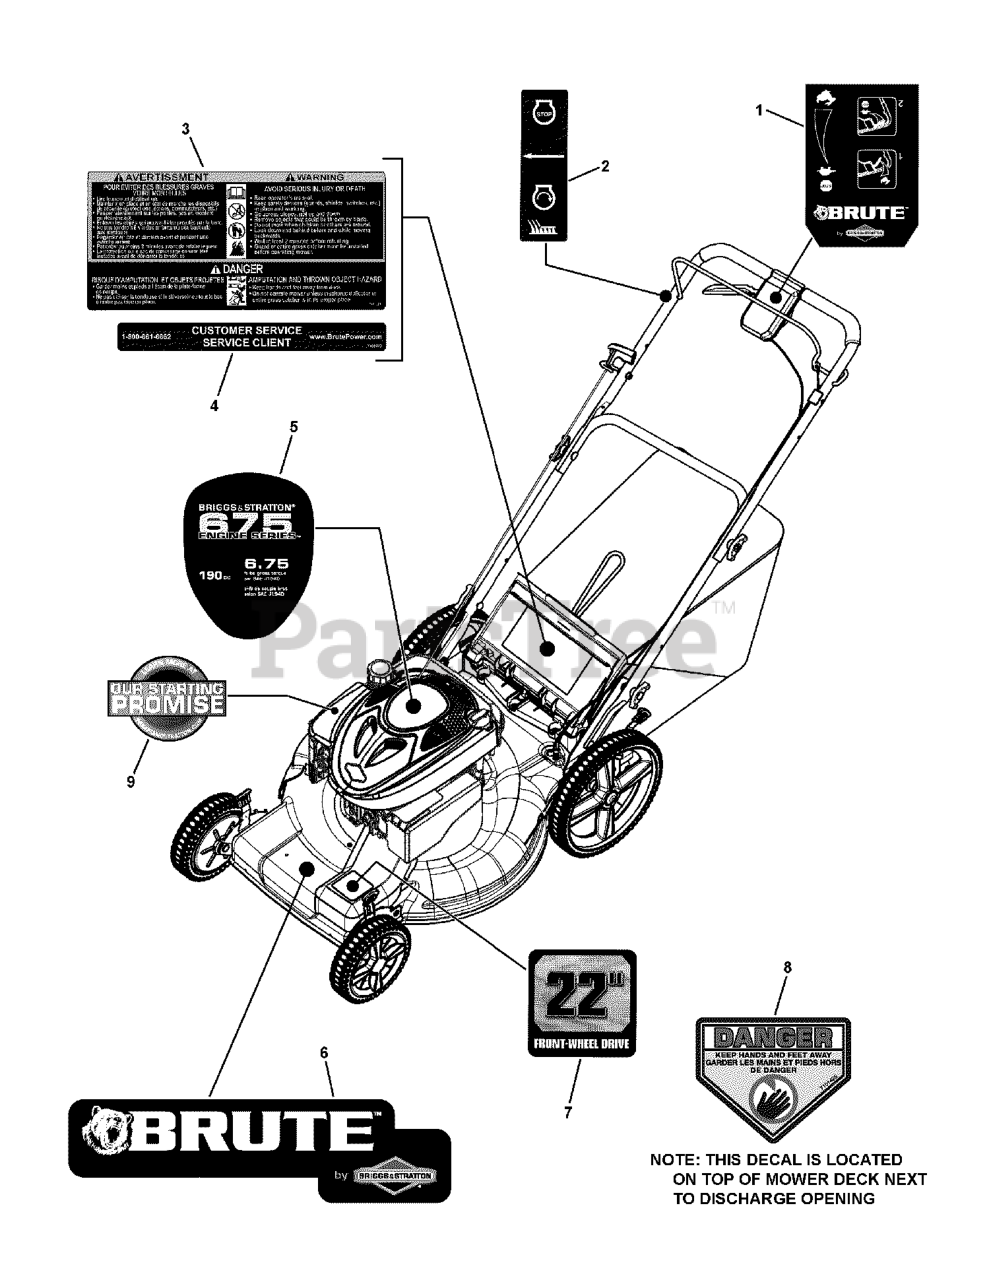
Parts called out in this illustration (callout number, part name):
1	DECAL, Control Head, 21" Brute
2	DECAL, OPC Bail International Symbol
3	DECAL, French/English, Walk-Behind Safety
4	DECAL, Customer Service, Brute, Canadian
5	DECAL, Engine, TP, Brute, 675, FC
6	DECAL, Brute Walk-Behind Mower
7	DECAL, 22" Front Wheel Drive Brute
8	DECAL, CPSC, French/English
9	LABEL, Starting Promise
